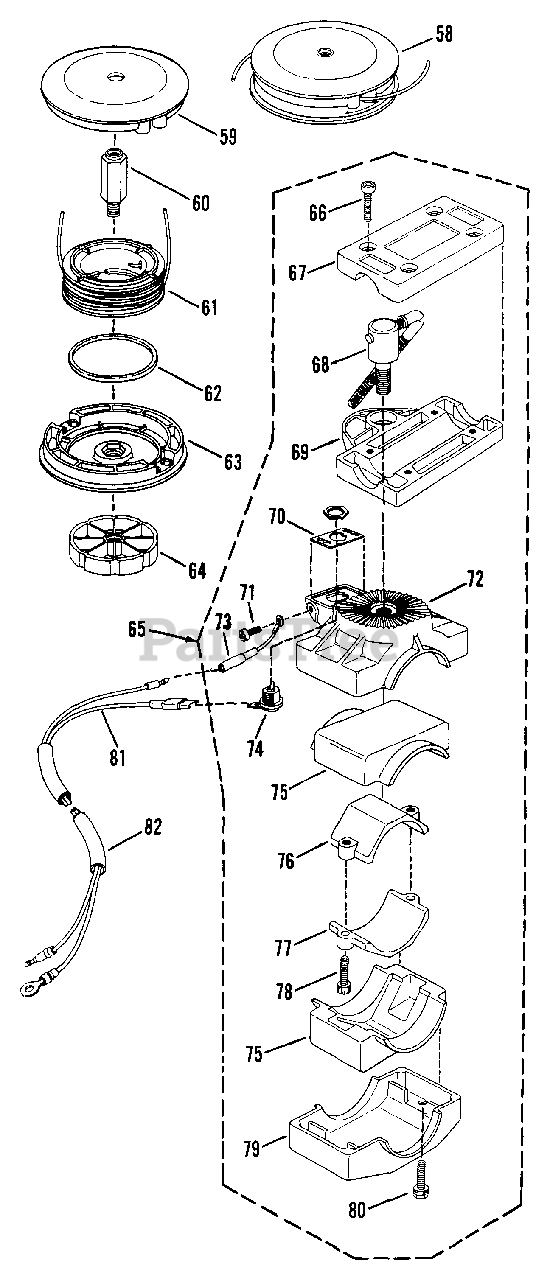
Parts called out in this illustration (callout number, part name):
58	MANUAL HEAD ASSM'Y.
59	HOUSING, Upper
60	ARBOR (10mm hole)
61	SPOOL & LINE
63	HOUSING, Lower
64	KNOB, Lock
65	SWIVEL HANDLE ASSM'Y.
66	SCREW, M5 x 20mm, Allen Hd.
67	JOINT "A", Handle
68	LOCK HANDLE
69	JOINT "B", Handle
70	PLATE, Switch
71	SCREW, M5 x 10mm
72	JOINT "D", Handle
73	LEAD, Wire (Ground)
74	SWITCH, Stop
75	RUBBER, Vibro (P)
76	FITTING "A", Tube
77	FITTING "B", Tube
78	SCREW, M6 x 25mm, Allen Hd.
79	JOINT "C", Handle
80	BOLT, M6 x 30mm, Hex
81	WIRE LEADS
82	TUBE, Wire Leads
